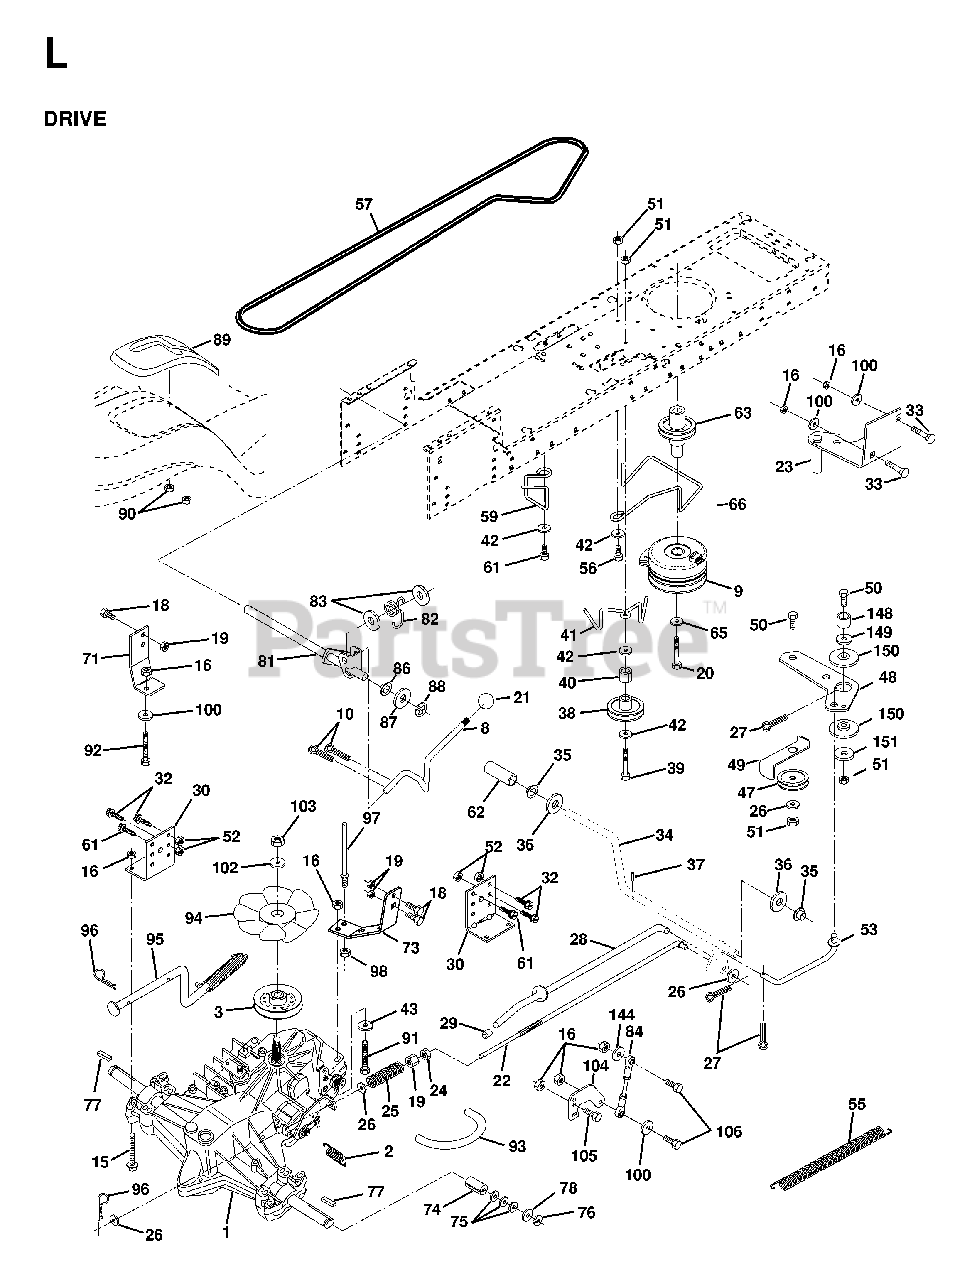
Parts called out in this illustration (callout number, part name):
1	TRANSAXLE ASSEMBLY
2	SPRING BRAKE
3	PULLEY, TRANSAXLE
8	ROD SHIFT FENDER
9	CLUTCH, ELECTRIC
10	PIN COTTER
15	BOLT HEX 5/16-18 GR 5
16	NUT.71038.31-18.HEX.NYLOCK
19	NUT
20	BOLT HEX
21	PISTOL KNOB
22	ROD BRAKE HYDRO
23	BRACKET, ASM CLUTCH MTG
24	NUT
25	SPRING ROD LT
27	COTTER PIN
28	ROD BRAKE PARK LT
29	PLUNGER CAP
30	BRACKET TRANSAXLE
32	BOLT
33	BOLT
34	SHAFT, FOOT PEDAL
35	BEARING.NYLON
36	WASHER LT
37	DRIVE PIN
38	PULLEY.IDLER.FLAT
41	KEEPER, BELT IDLER
42	WASHER
47	IDLER PULLEY
48	BELLCRANK, CLUTCH
49	RETAIN BELT
50	BOLT
51	LOCKNUT
52	LOCKNUT
53	LINK, CLUTCH LT
55	SPRING, RETURN LT
59	KEEPER CENTER SPAN
61	SCREW
62	PEDAL COVER T
63	ENGINE PULLEY
65	LOCKWASHER
66	BELT KEEPER
68	STRAP LH TORQUE
73	STRAP TORQUE RH HYDRO
74	SPACER SPLIT
76	E-RING LT
77	SQUARE KEY
82	SPRING,TORSION
83	WASHER
88	KLIP RING
89	SHIFT CONSOLE
92	HEX BOLT
93	FUEL LINE
94	FAN 7" HYDRO
95	CONTROL ARM, BYPASS HYDRO
96	RETAINER M
97	KEEPER BELT RH
100	WASHER M
103	NUT.HEX.1/2-20
104	CONTROL ARM
106	BOLT.5/16-18X1-1/4 FULL.THREAD
144	WASHER
148	GUIDE
149	SPACER RETAINER
150	BUSHING NYLON COLLERED
151	WASHER 12/32X2X10GA
